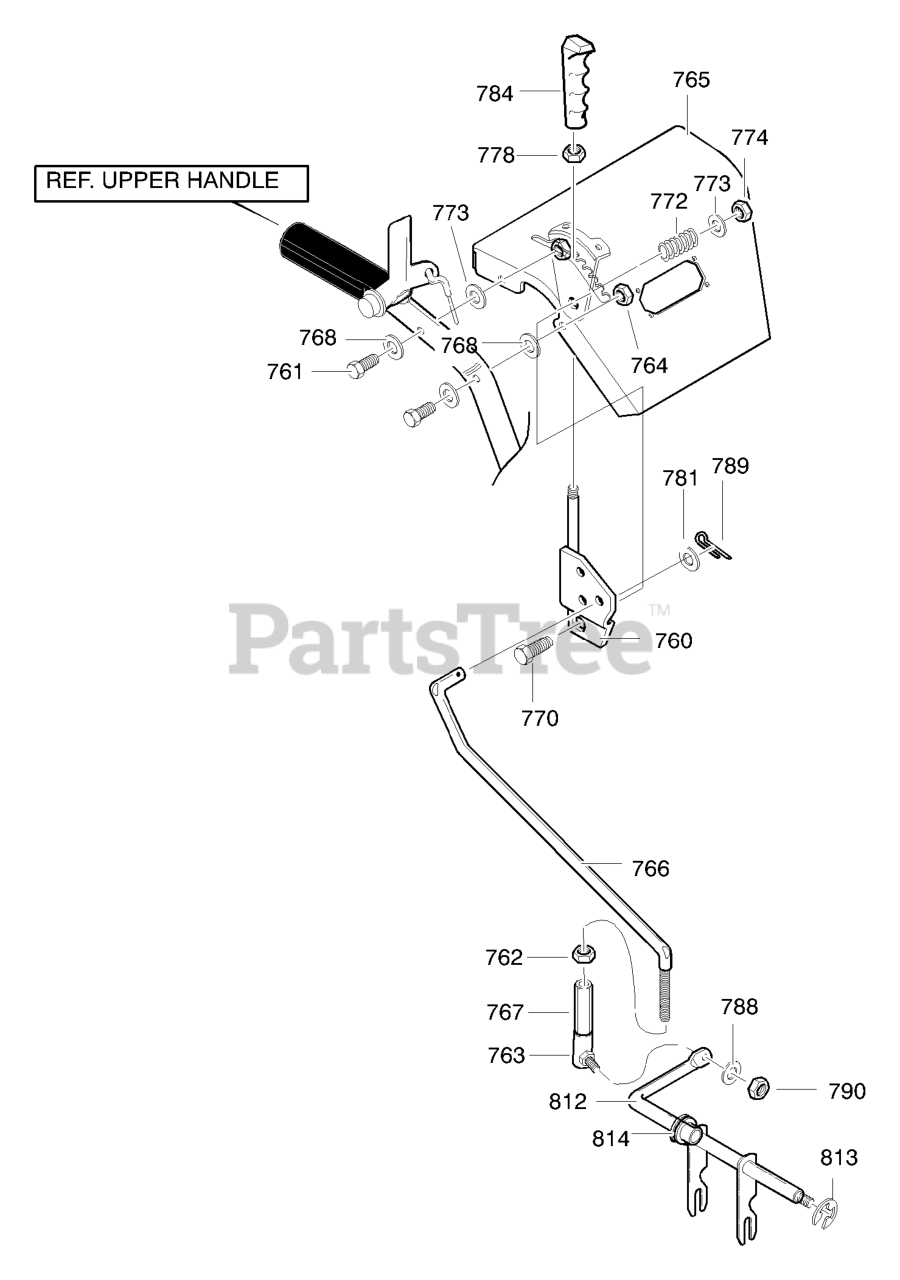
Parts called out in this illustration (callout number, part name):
760	HANDLE ASSY SPD CTRL
761	SCREW, 5/16-18 x 1.75
762	NUT, 5/16-24
763	JOINT, BALL
764	NUT, 5/16-18
765	ASSY. BAY LT
766	ROD, SPEED CONTROL
767	ADAPTER, ROD
768	WASHER
770	SCREW 3/8-16X2.00
773	FLATWASHER
774	NUT, 3/8-16
778	NUT, JAM 3/8-16
781	FLATWASHER
784	HANDLE, GRIP
788	FLATWASHER
789	PIN, COTTER
812	ROD, ASSY YOKE
813	RING, RETAINER
814	BEARING, FLANGE
